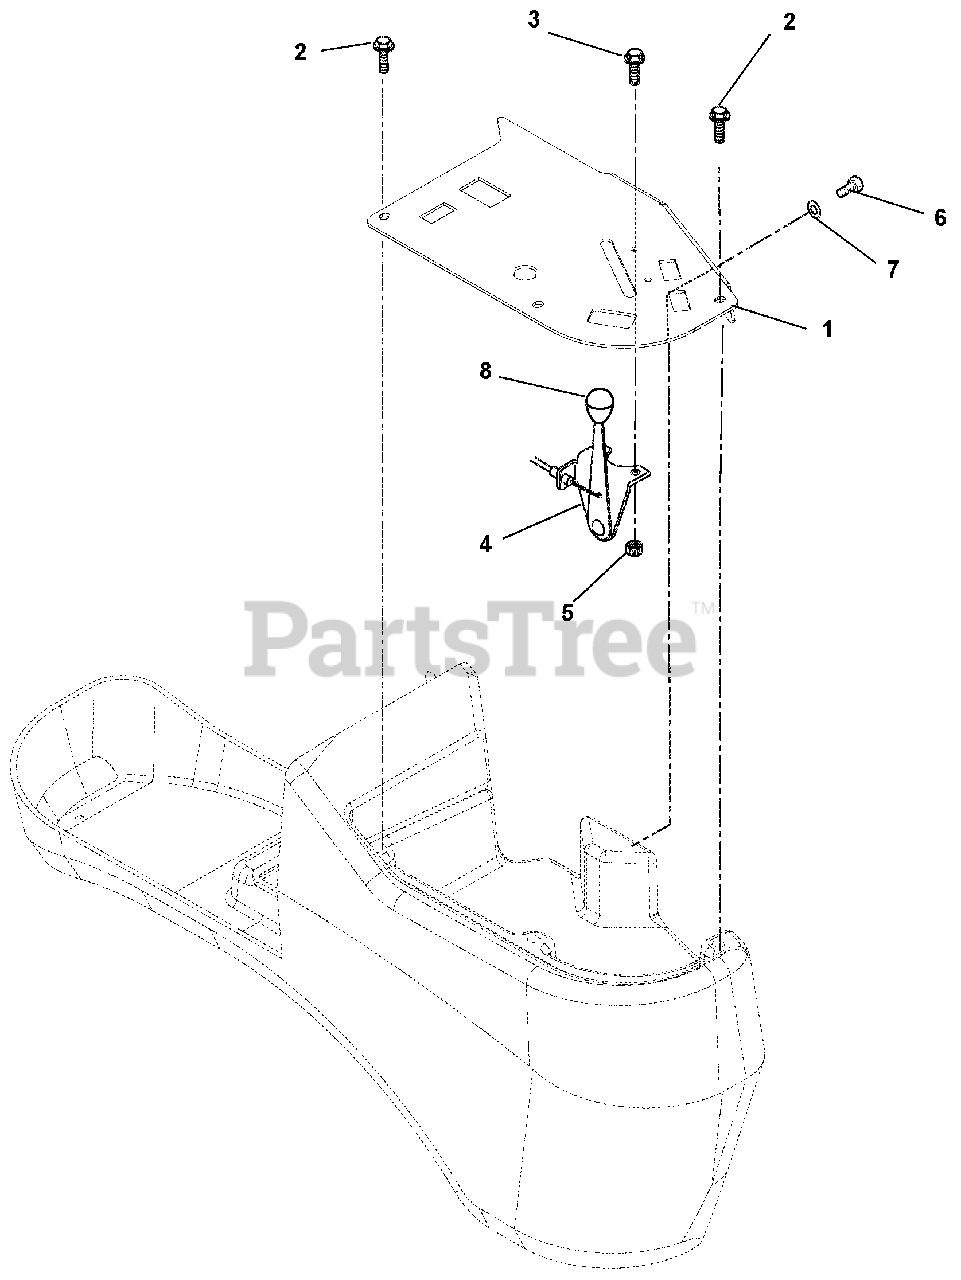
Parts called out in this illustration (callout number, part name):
1	Panel, Control
2	Screw, Machine 10-24 x .38 Hex Washer Head, Stainless
3	Screw, Machine 10-24 x .50 Hex Washer Head
4	Cable, Pro-Control Throttle
5	Nut, Locking Nylon 10-24 With Insert
6	Bolt, Hex .31-18 x .75 Grade 5
7	Washer, Flat Steel .38 x .875 x .083
8	Knob, Control, Black .38-16 x .62
